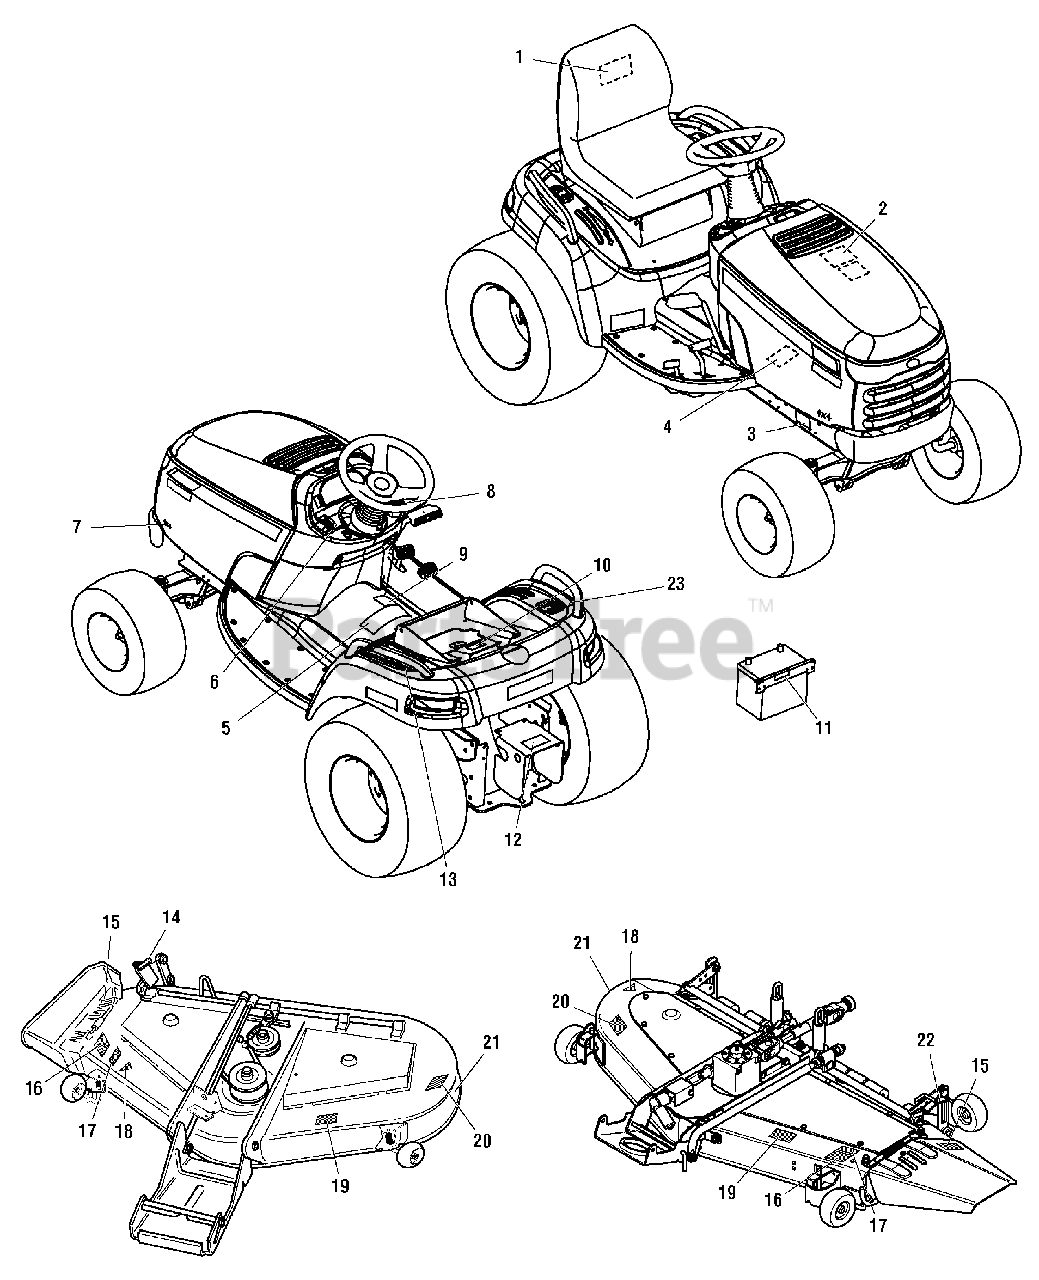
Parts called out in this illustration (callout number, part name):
1	DECAL, USA Logo
2	DECAL, Belts & Blades
3	DECAL, Serial Number
3	DECAL, Power Mass (Export)
4	DECAL, Rotating Fan Blades
4	DECAL, Rotating Fan Blades (Export)
5	DECAL, Operating Instructions
5	DECAL, Operating Instructions (Export)
6	DECAL, Throttle Speed
7	DECAL, 4 X 4, Simplicity
7	DECAL, 4 X 4, (Massey Ferguson & AGCO)
8	DECAL, Ignition Switch
9	DECAL, Hydraulic Lift
10	DECAL, Transmission Release Valve
11	DECAL, Warning Battery Ground
12	DECAL, Danger, Rotating Parts
12	DECAL, Danger, Rotating Parts (Export)
13	DECAL, PTO Selector Position (540 PTO Models Only)
14	DECAL, Height of Cut, 54" Deck
15	DECAL, Cutting Line
16	DECAL, Danger (Chute in Place)
18	DECAL, OPEI Certified
19	DECAL, Belt Installation, 54"
19	DECAL, Belt Installation, 60"
19	DECAL, Belt Installation, 48"
20	DECAL, Danger, (Hands Under Deck)
21	DECAL, Free Floating Mower
22	DECAL, Height of Cut, 60" & 48" Mower Decks
23	DECAL, 4WD Rollover
